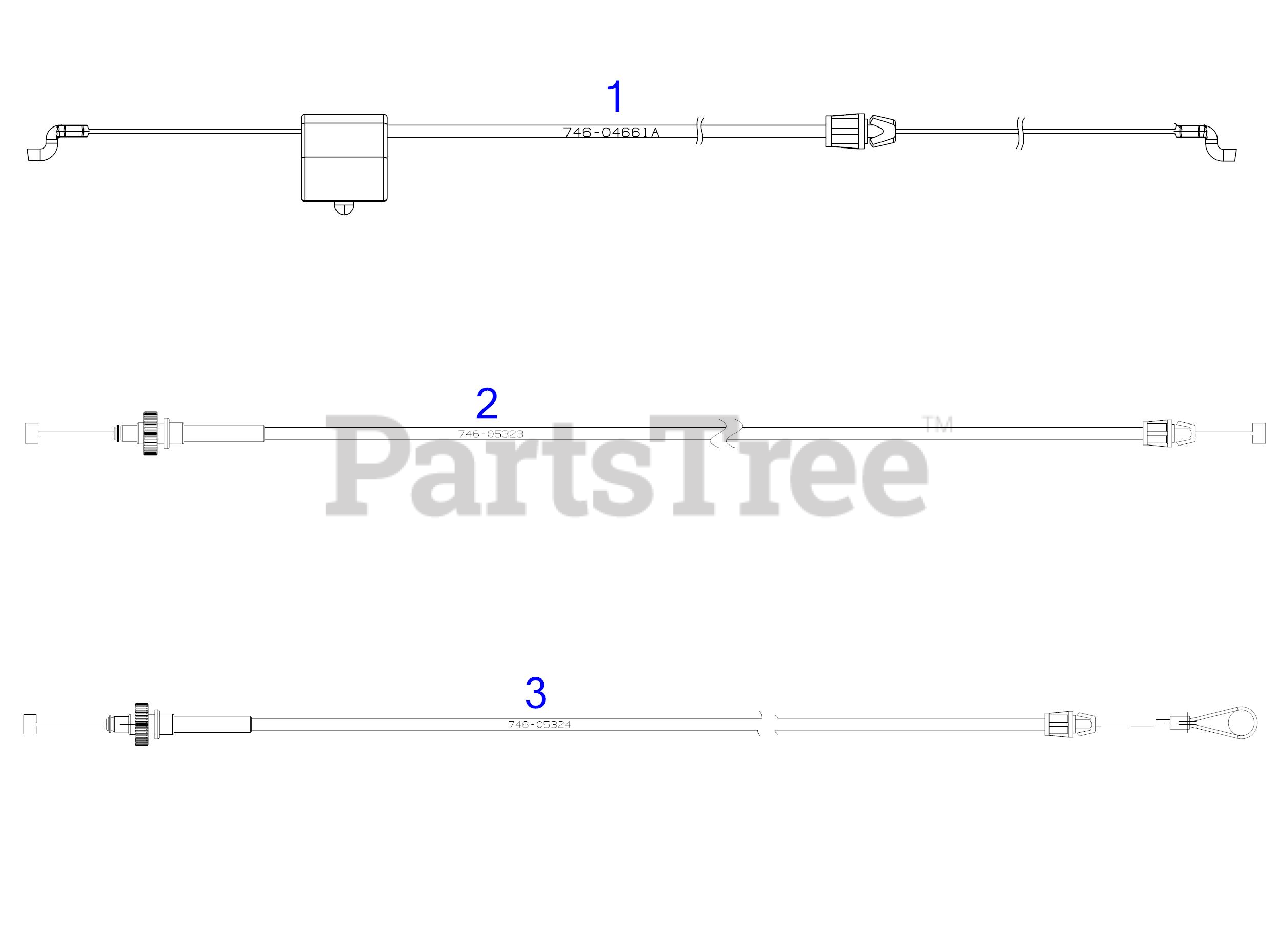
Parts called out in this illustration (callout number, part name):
1	CONTROL CABLE 37.58"
2	CONTROL CABLE FWD
3	CONTROL CABLE RWD
